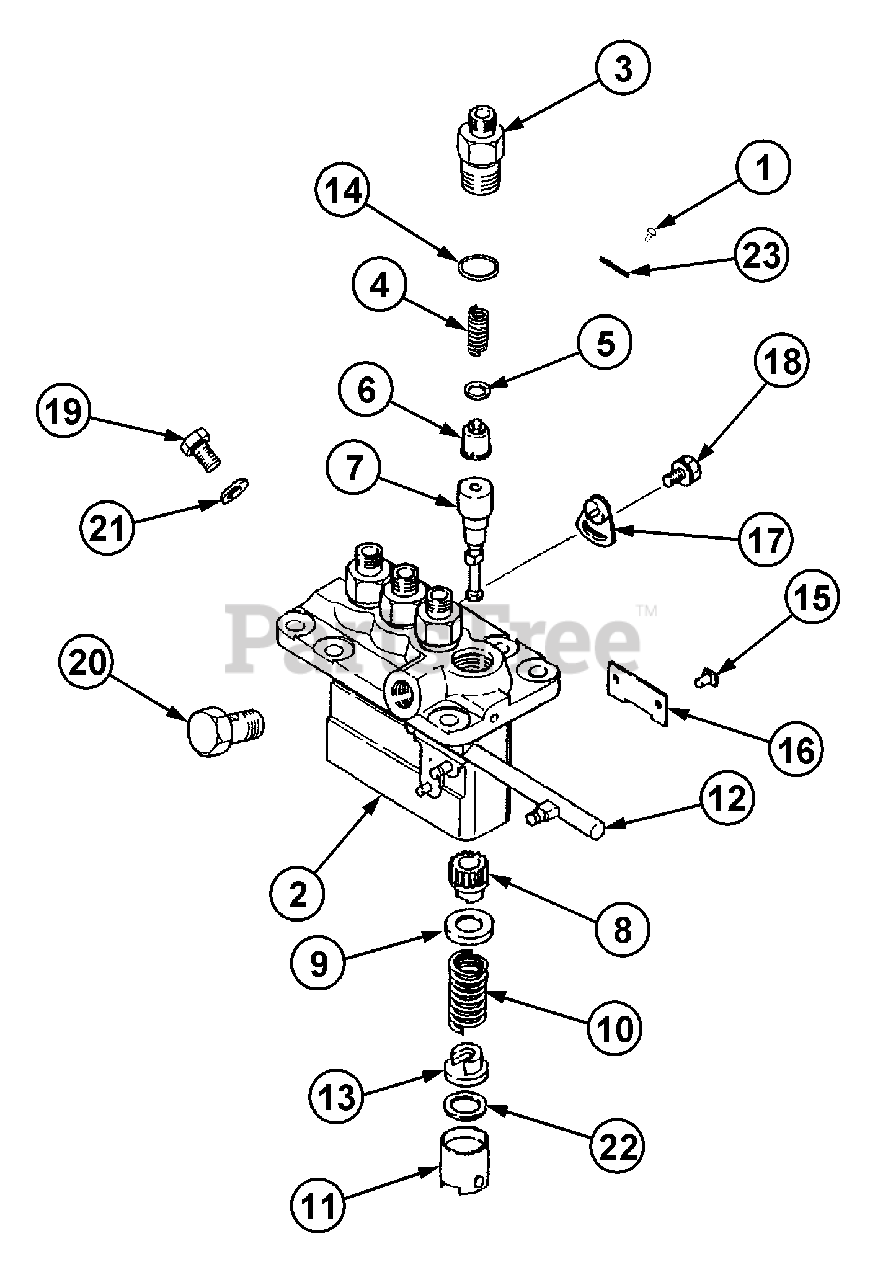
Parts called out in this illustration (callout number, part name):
1	Rivet
2	Housing Sub Assy
3	Holder, Delivery
4	Spring, Delivery
5	Gasket, Delivery
6	Valve Sub Assy
7	Element Sub Assy
8	Sleeve, Control
9	Seat, Spring Upper
10	Spring, Plunger
11	Tappet Sub Assy
12	Rack Assy, Control
13	Seat, Spring Lower
15	Pin, Tappet Guide
16	Plate
17	Plate, Adjusting
19	Screw, Air Bleeder
20	Screw, Hollow
21	Washer, Pipe Union
22	Plate, Tappet Shim, t=0.6
23	Plate, Name
